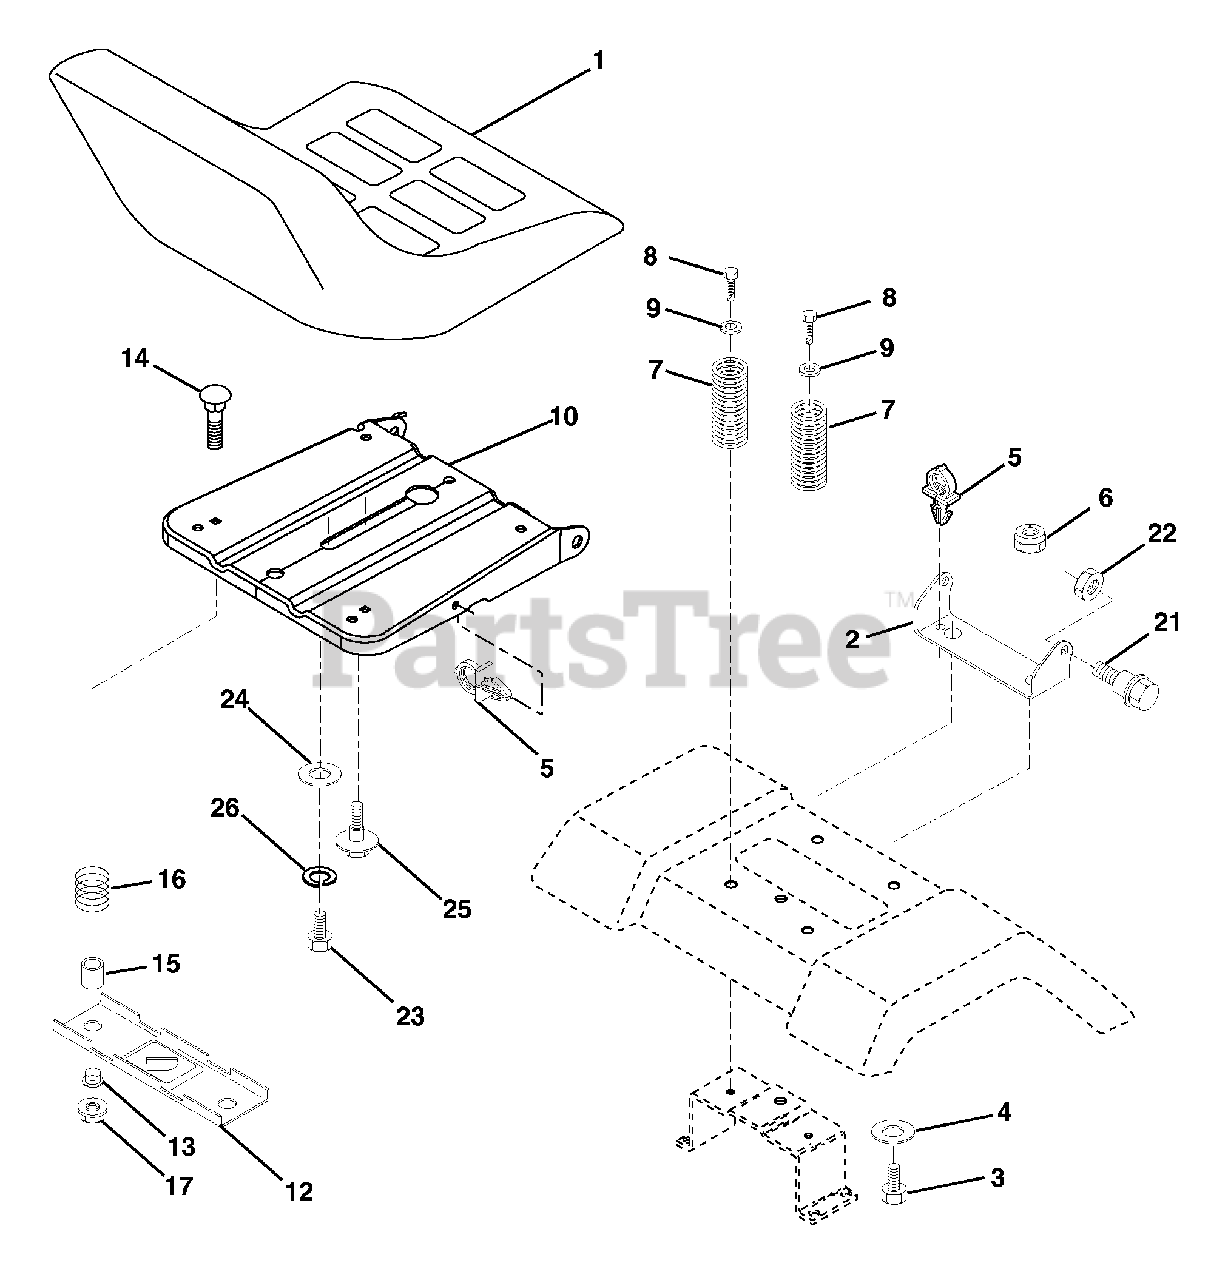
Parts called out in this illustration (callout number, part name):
1	Seat
2	Bracket Pnt Pivot Seat (blk)
3	Bolt
4	Washer 13/32 x 1 x 10 Ga.
5	Clip Push-In Hinged
6	Nut
7	Spring Seat Cprsn 2 250 Blk Zi
8	Screw 3/8-16 x 1.5
9	Washer 13/32 x 1 x 14 Ga.
10	Pan Pnt Seat (blk )
12	Bracket Pnt Mounting Switch
13	Bushing Snap Blk Nyl 50 Id
14	Bolt Rdhd Sht Nk 1/4-20 x 1-1/2
15	Spacer Split 28 x 96 Yel Zinc
16	Spring Cprsn 1 27 Blk Pnt
17	Nut Lock 1/4 Lge Flg Gr. 5 Zinc
21	Bolt Shoulder 5/16-18 unc Blkz-2A
22	Nut
23	Bolt Hex Black
24	Washer 17/32 x 1-3/16 x 12 Ga.
25	Bolt Shoulder 5/16-18 x 62
26	Lockwasher
